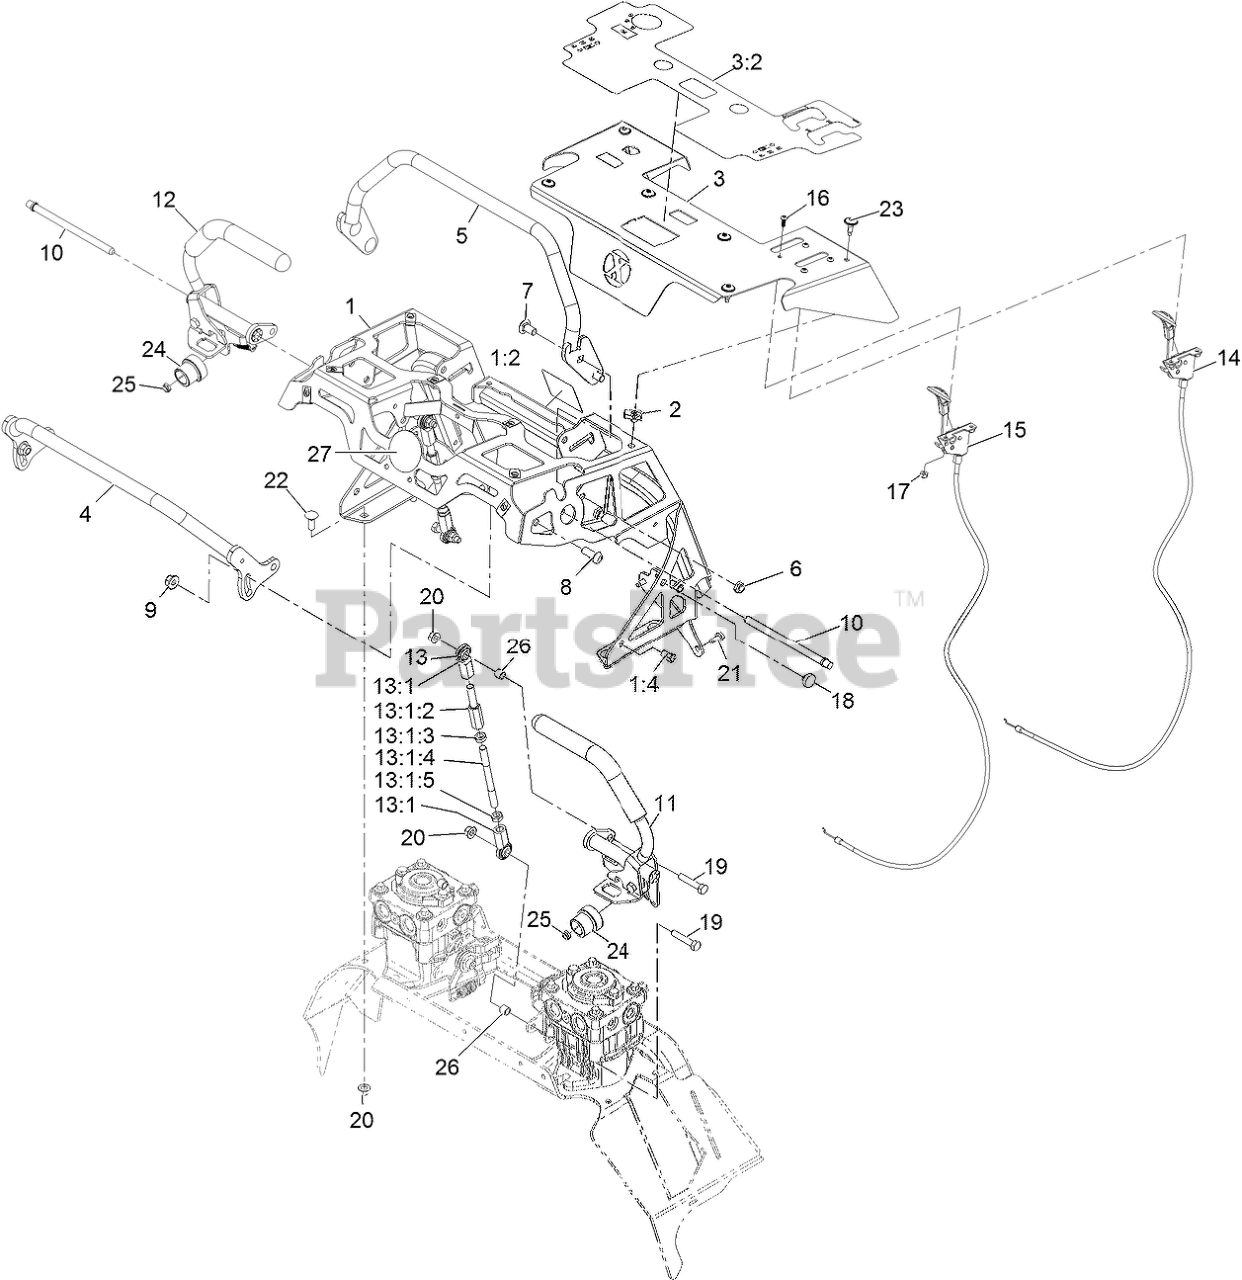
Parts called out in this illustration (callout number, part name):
1	ASM-Ctrl Tower
1:2	Decal-HYD Fluid Warn
1:4	Nut-Clinch,Hex
3	ASM, Control Panel W/ Decals
3:2	Decal-Control Panel Non-EFI
4	Weld, Front Ref Bar
5	Weld, Rear Ref Bar
7	SCREW-CARR
8	SCREW-HSBH
9	NUT-HF, NI
10	PIN, PIVOT
11	ASM, Motion Control, Lt
12	ASM, Motion Control, Rt
13	ASM, Linkage
13:1	ASM, Motion Control Link
13:1:2	ROD-ADJUSTMENT
13:1:3	NUT-HEX JAM, LH
13:1:4	Link, Motion Control
13:1:5	NUT-HJ
14	CONTROL, CHOKE
15	CONTROL, THROTTLE
16	SCREW, BHCS
17	NUT-LOCK, NI
19	SCREW-HH
20	NUT-HF, NI
21	SCREW-HWH
22	SCREW-CARR
23	Screw, Torx
25	NUT-LOCK, NI
27	Decal-Cover
